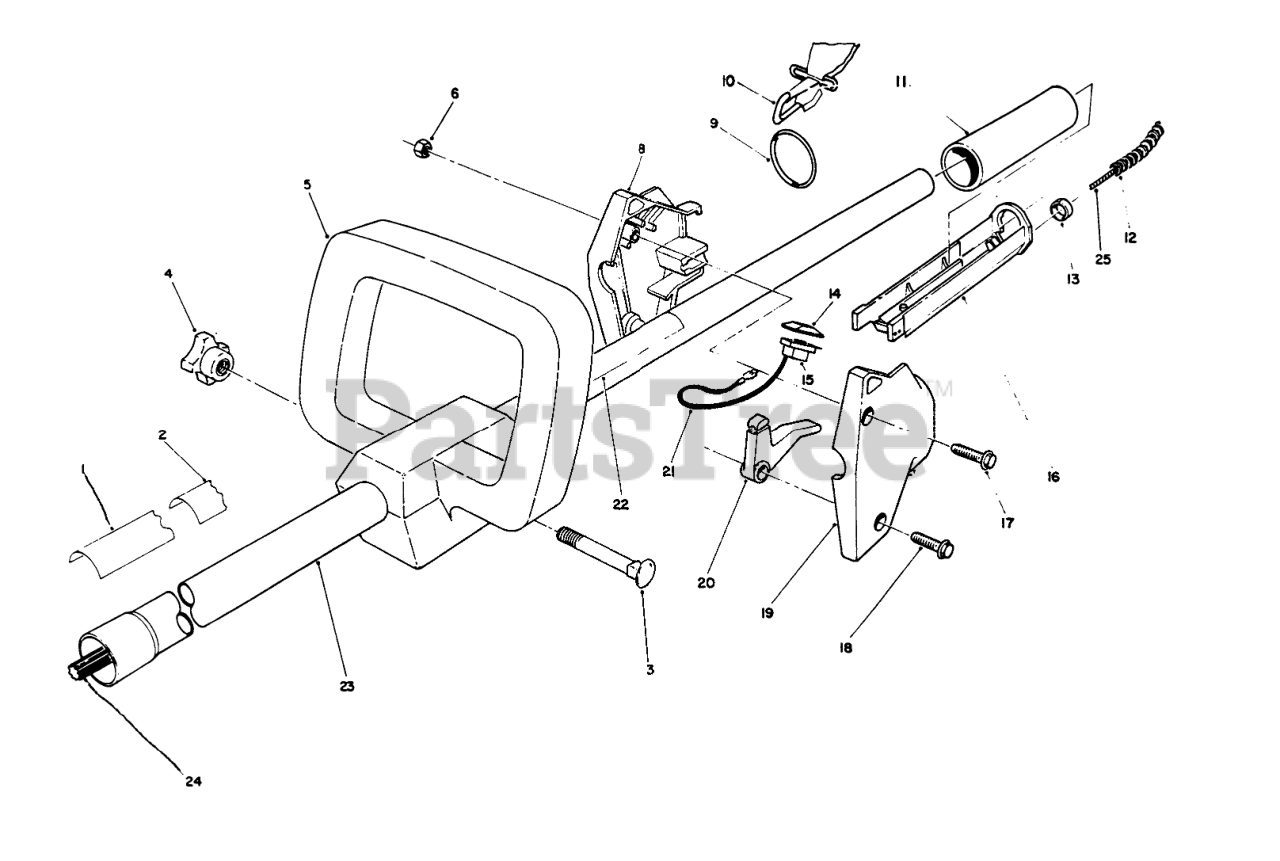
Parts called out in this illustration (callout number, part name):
1	Decal-TC 3110
2	DECAL-INSTRUCTION
3	BOLT-CARRIAGE
4	Knob
5	HANDLE SECONDARY
6	NUT-LOCK, NI
8	THROTTLE HSG.R H
9	RING-HARNESS
10	Harness-Shoulder
11	GRIP - RUBBER
12	CABLE COVER
13	RING FITTING
14	SWITCH COVER-BLACK
15	SWITCH
16	TROUGH 1"
18	SCREW-HWH
19	THROTTLE HSG. L H
20	THROTTLE LEVER
21	WIRE ASM
22	Decal Danger
23	TUBE ASSEMBLY
24	SPLINE SHAFT
25	THROTTLE CABLE
